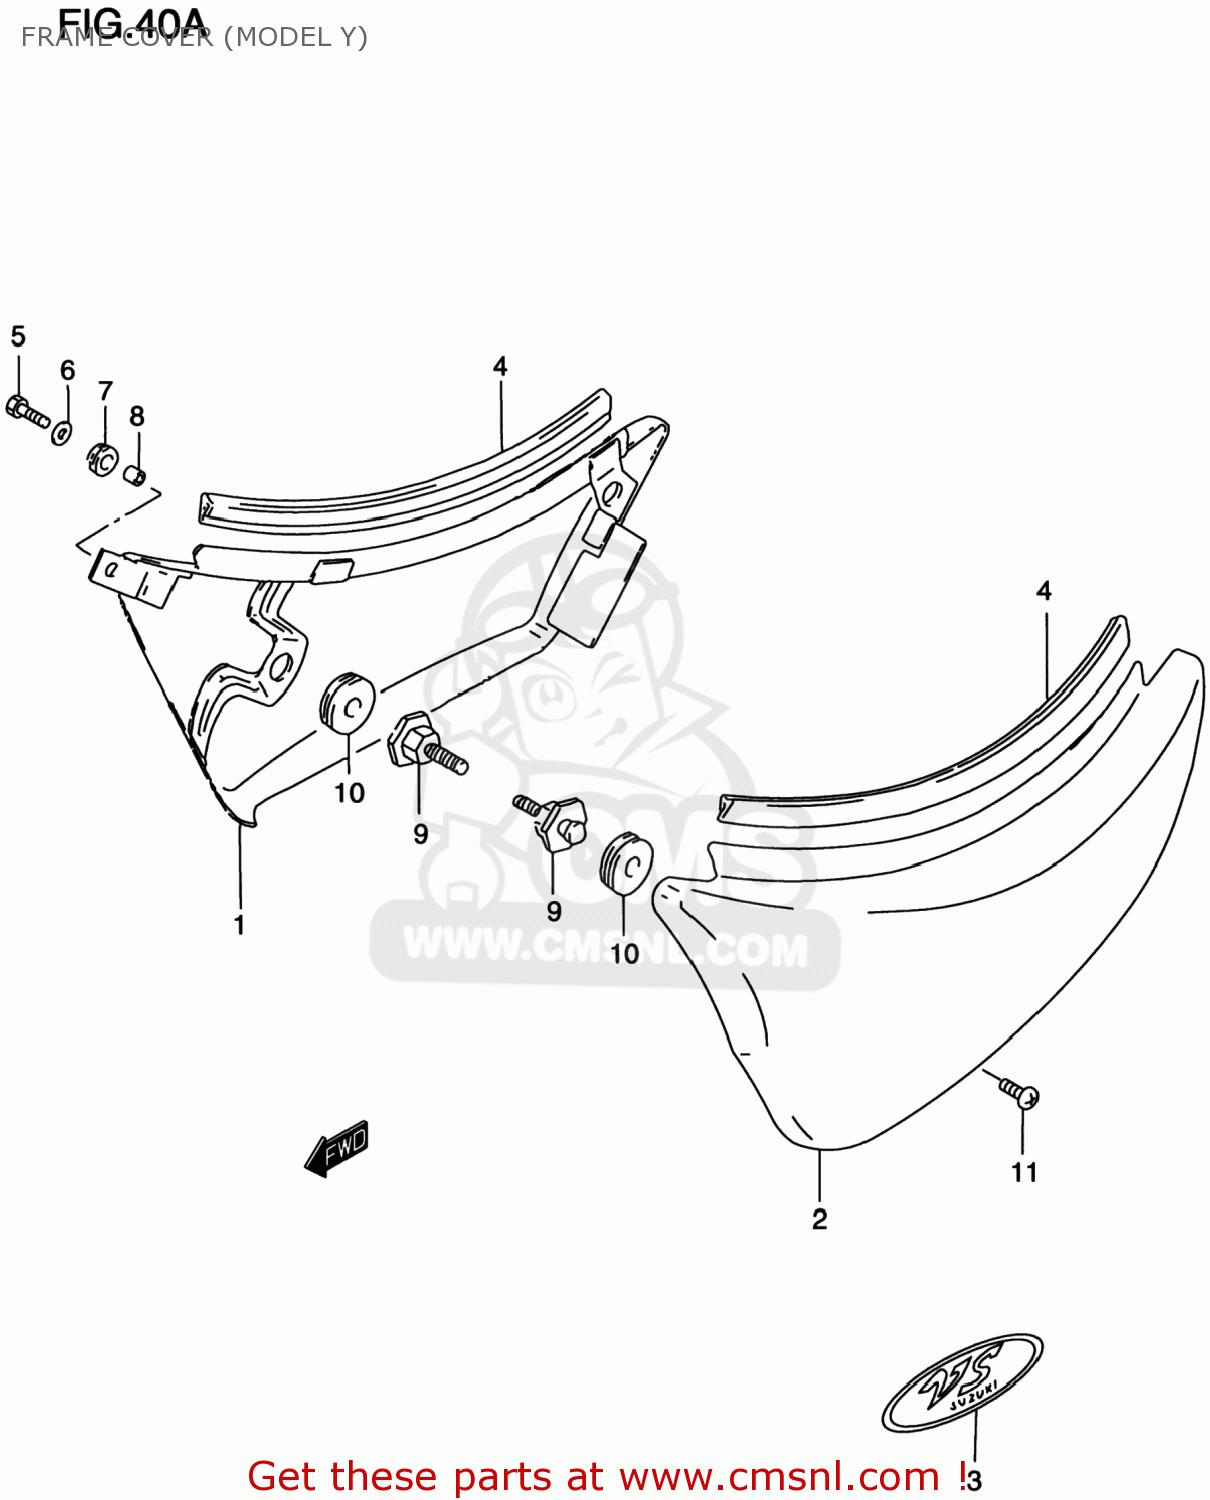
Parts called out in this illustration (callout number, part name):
1	COVER,FRAME,R(RED)
2	COVER,FRAME,L(RED)
3	EMBLEM,FRAME COVER
4	MOLDING
5	BOLT
6	WASHER(6.5X18X1.6)
7	CUSHION
8	SPACER(6.1X8X5.2)
9	BOSS,FRAME COVER
10	CUSHION
11	SCREW 6X10
